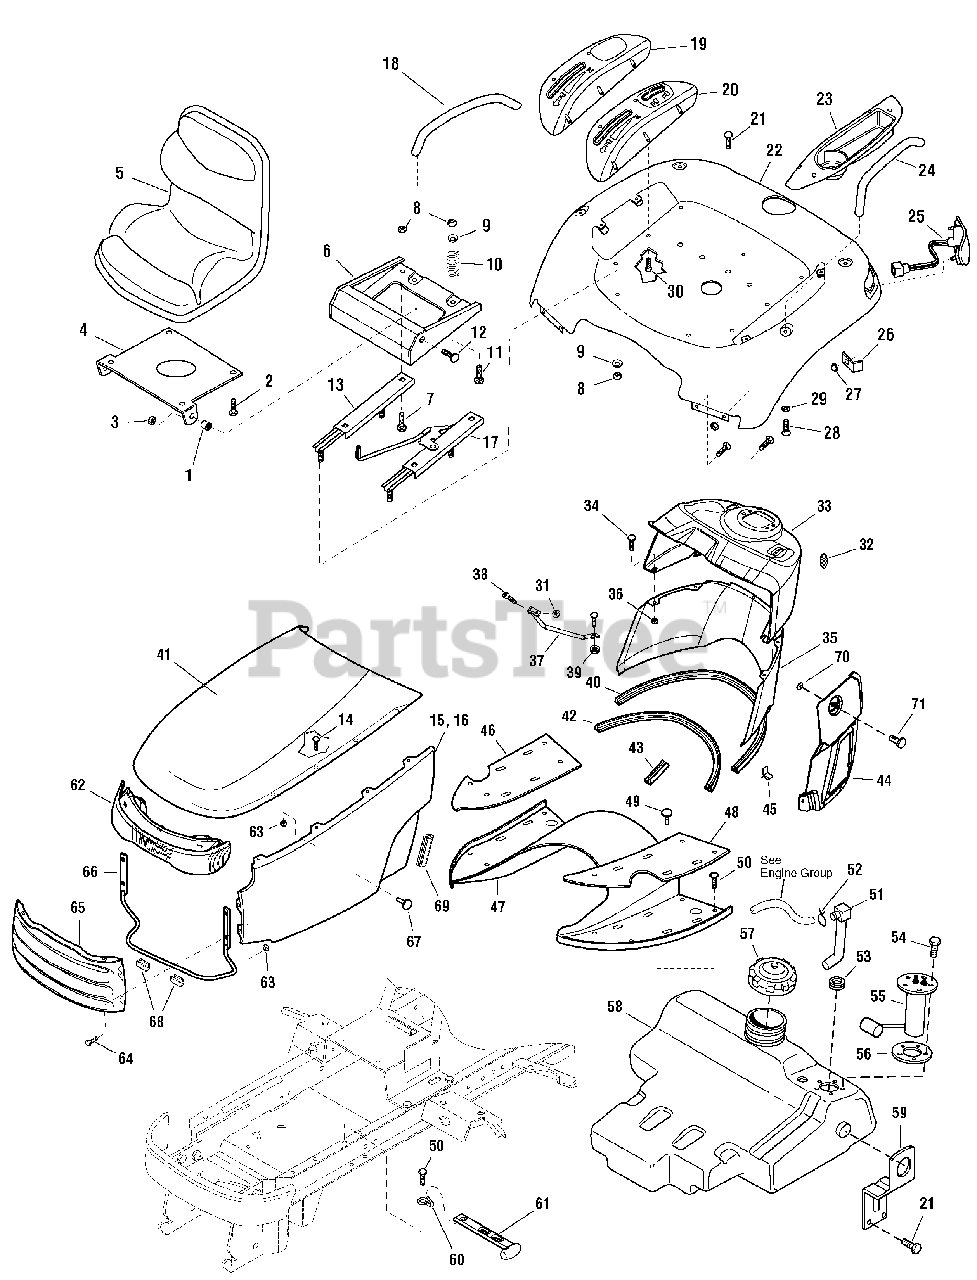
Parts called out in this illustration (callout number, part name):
2	SCREW, Hex, Flange Whiz Lock, Dog Point, 5/16-18 x 1
3	NUT, Hex, Flange ESNA Lock, Black 3/8-16
5	SEAT, Black
6	SUPPORT, Seat Lower
7	CARRIAGE BOLT, Black, 5/16-18 x 3/4
8	NUT, Nut, Flange Lock, ESNA, 5/16-18
9	LOCKWASHER, Black
10	SPRING, Seat
11	CARRIAGE BOLT, Black, 5/16-18 x 1
12	CARRIAGE BOLT, Black, 3/8-16 x 1
13	SLIDE, Seat
14	CAPSCREW, Hex, Head, 1/4-20x 5/8
15	PANEL, Side RH
15	PANEL, Side RH, Legacy XL
16	PANEL, Side LH
16	PANEL, Side LH, Legacy XL
17	SLIDE, Seat, LH
18	HANDLE, Grab, RH, Black
19	POD, Legacy XL, 2WD
20	POD, Legacy XL, 4WD
21	CAPSCREW, Hex, Washer Head, Taptite, Black, 5/16-18 x 3/4
22	DECK, Seat, Legacy XL
23	POD, Legacy XL, LH
24	HANDLE, Grab, LH, Black
25	TAIL LIGHT ASSEMBLY
27	NUT, Push, Black, 5/16
28	CAPSCREW, Hex Head, Black, 5/16-18 x 5/8
29	WASHER, Black, 5/16
30	CAPSCREW, Hex Washer Head, #12-24 x 5/8
31	NUT, Nylock, # 10-24
32	PLUG, Dashboard, Diesel
33	DASH, Upper, Black, Diesel
33	DASH, Upper, Black, Gas
34	CARRIAGEBOLT, Black, 1/4-20 x 5/8
35	DASH, Lower, Black, Diesel
35	DASH, Lower, Black, Gas
36	NUT, Hex, KEPS, Black, 1/4-20
37	ROD, Dash Support
38	SCREW, Phillips, Pan Head, Black, #10-24 x 1
39	NUT, Hex, Keps, Black, 5/16-18
40	EDGING, Rubber, Black, 31" Long
41	HOOD & SCREEN ASSEMBLY
42	EDGING, Rubber, Black, 23" Long
43	EDGING, Rubber, Black, 2-5/8" Long
44	COVER ASSEMBLY, Dash, Black
46	PAD, Footrest, RH
47	TUNNEL, Legacy XL
48	PAD, Footrest, LH
49	FASTENER, Panel
50	CAPSCREW, Hex, Washer Head, Taptite, Black, 1/4-20 x 1/2
51	ELBOW & TUBE ASSEMBLY
52	CLIP
54	SCREW, Pan Head, Torx, SEMS, #10-32 x 1/2
55	SENDER, Fuel
57	CAP, Fuel, Diesel
57	CAP, Fuel, Gas
58	TANK, Fuel, Diesel
58	TANK, Fuel, Gas
59	SUPPORT, Fuel Tank
60	HOOK
61	STRAP, Hood, Black Rubber
62	HEADLIGHT ASSEMBLY
63	NUT, Hex, Flange Whiz Lock, Black, 1/4-20
64	CAPSCREW, Hex, Whiz Lock, Black, 1/4-20 x 1
65	GRILL, Legacy XL
66	ROD, Hood Hinge
67	SCREW, Binding
69	EDGING, Side Panel
70	NUT, Push
71	SCREW, Quarter Turn
